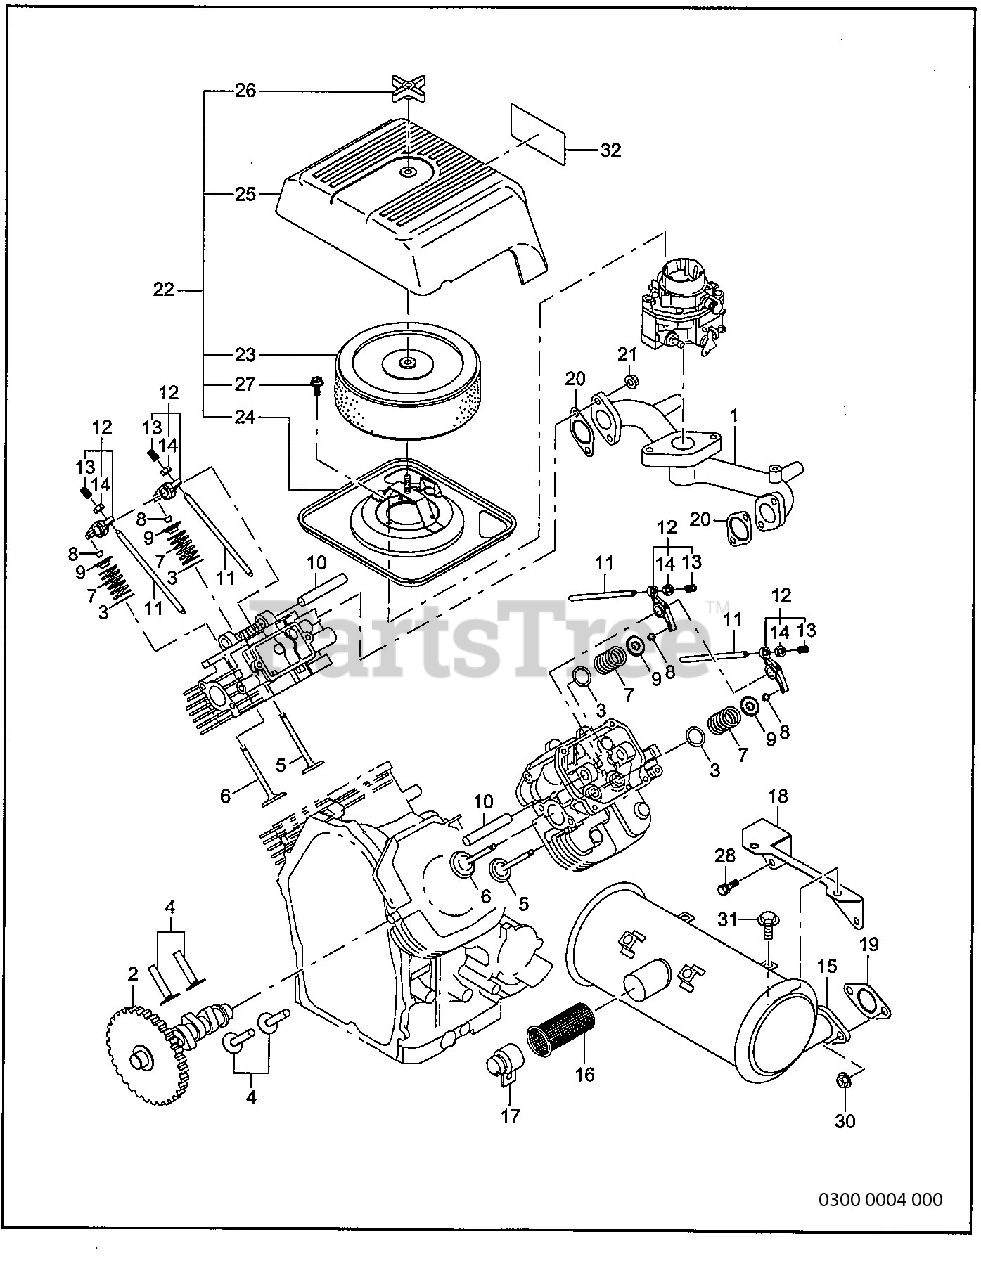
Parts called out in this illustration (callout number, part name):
1	INTAKE MANIFOLD
9	SPRING RETAINER
12	ROCKER ARM ASSY
13	ADJUSTING SCREW
16	SPARK ARRESTER
18	BRACKET MUFFLER
19	GASKET EXHAUST
20	GASKET, intake manifold
20	GASKET, muffler
22	AIR CLEANER ASSY
23	CLEANER ELEMENET ASSY
24	CLEANER BASE ASSY
28	BOLT and WASHER ASSY
31	FLANGE BOLT
32	LABEL (TRADE MARK)
